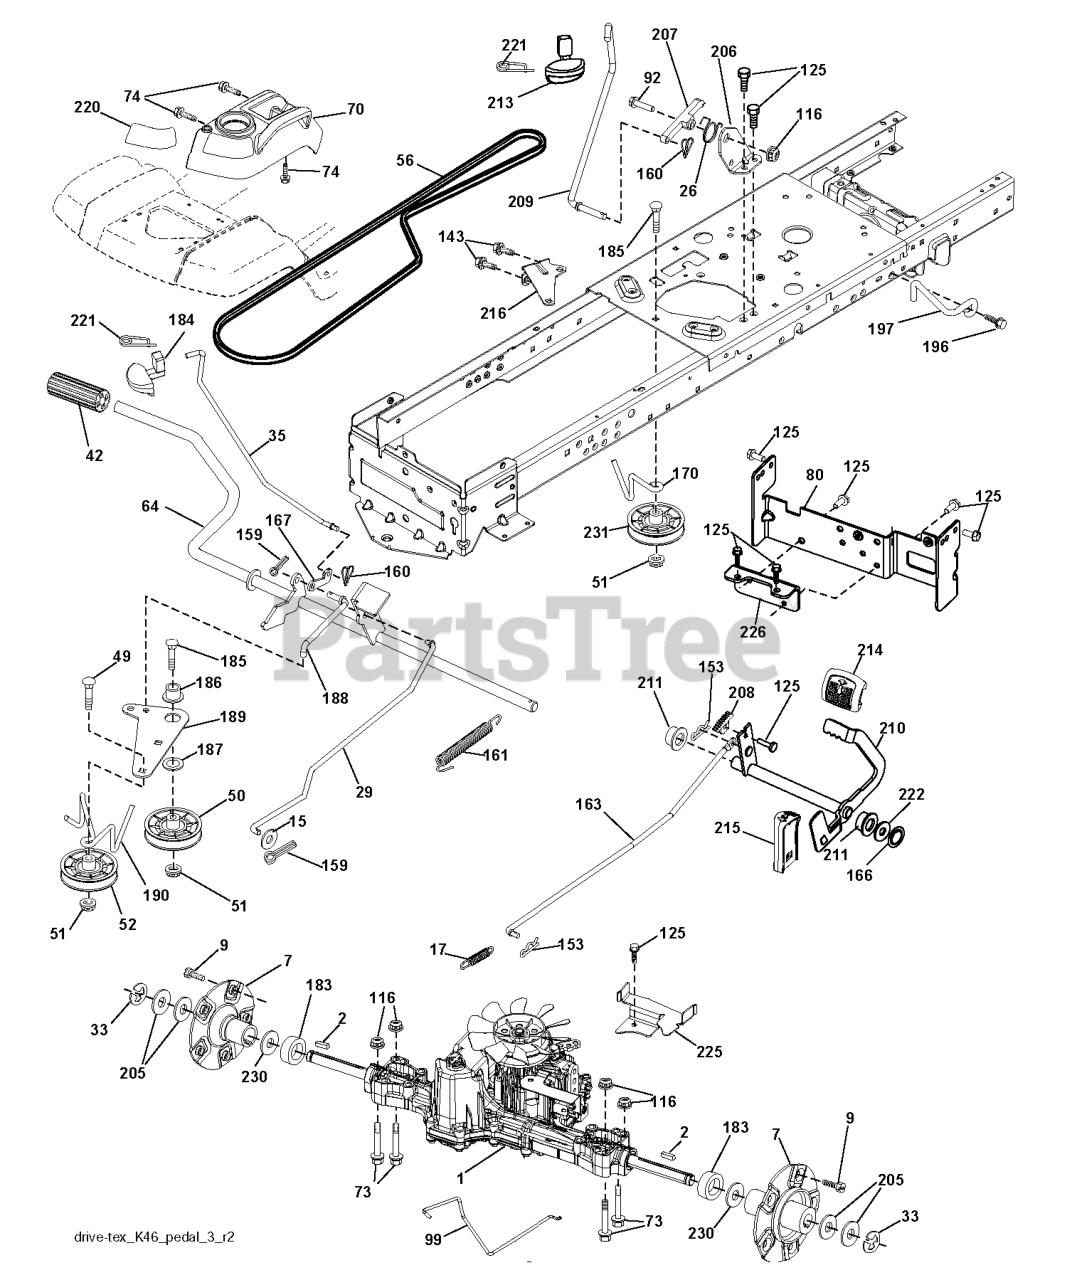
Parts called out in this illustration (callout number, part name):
2	KEY.SQUARE.187X2.500
7	HUB.ASM.WHEEL.REAR.22"
15	WASHER
17	SPRING.BRAKE.K46.GREEN
26	SPRING.RETURN.CRUISE
29	ROD.BRAKE.K46
35	ROD.BRAKE.PARKING.GT.H
42	PEDAL COVER T
50	IDLER.FLAT.910.OFFSET
51	NUT LOCK FLG 3/8-16 UNC
52	IDLER.V-GROOVE.910.OFFSET
56	V-BELT.MOWER.92.40.42/K46
64	SHAFT.ASM.PEDAL.BRK.CNTR
70	RP CONSOLE.ASM.PCH.W/TB
73	BOLT HEX 5/16-18 GR 5
74	SCREW.HI-LO.CONSOLE
80	STRAP TORQUE.ASM.K46/18"TEX
92	BOLT
99	ROD.SPRING.BYPASS.K46.LT.Z
116	NUT LOCK HEX FLANGE 5/16-18
125	SCREW
143	Screw 5/16-18 x 1/2 Hex, Self Tapping 5/16-18 x 1/2
153	RETAINER M
159	COTTER PIN
160	RETAINER CLIP
161	SPRING, RETURN LT
163	ROD.CONTROL.PEDAL.K46
166	NUT.PUSH.625.2006
167	LATCH.BRAKE.SPRING
170	KEEPER.CENTER SPAN.1.688
183	SPACER.SPLIT.800X.350
184	HANDLE.PARKG.BRK.HUSQ X667
186	SPACER.RETAINER
187	WASHER 12/32X2X10GA
188	RP.LINK.CLUTCH.GROUND.DRIVE
189	BELLCRANK.GROUND.DRIVE.TEX.
190	KEEPER.BELLCRANK.DRIVE
196	SCREW 3/8-16X1
197	BRKT.ANIT-ROTATION.CLUTCH
206	BRKT.MOUNT.LATCH.CRUIS
207	LATCH.CONTROL.CRUISE
208	GEAR.SECTOR.CONTROL.CR
209	ROD.CONTROL.CRUISE.GT.
210	ROCKER.ASM.PEDAL.CONTR
211	BEARING.NYLON
213	KNOB.CONTROL.CRUSIE.HU
214	PEDAL.FORWARD.TEX.GT.4
215	PEDAL.REVERSE.TEX.GT.4
216	BRACKET.PULLEY.IDLER.W/TEX
220	REFLECTOR.RH.TEX GT
221	RETAINER.SPRING.CLIP.H
222	WASHER 21/32 X 1-1/4 X 10 GA.
225	KEEPER.BELT.TRANSAXLE.K46
226	BRACKET.MOUNT.TORQUE.K46.TLT
230	WASHER.HARDENED
231	IDLER.V-GROOVE.1.688.OFFSET
